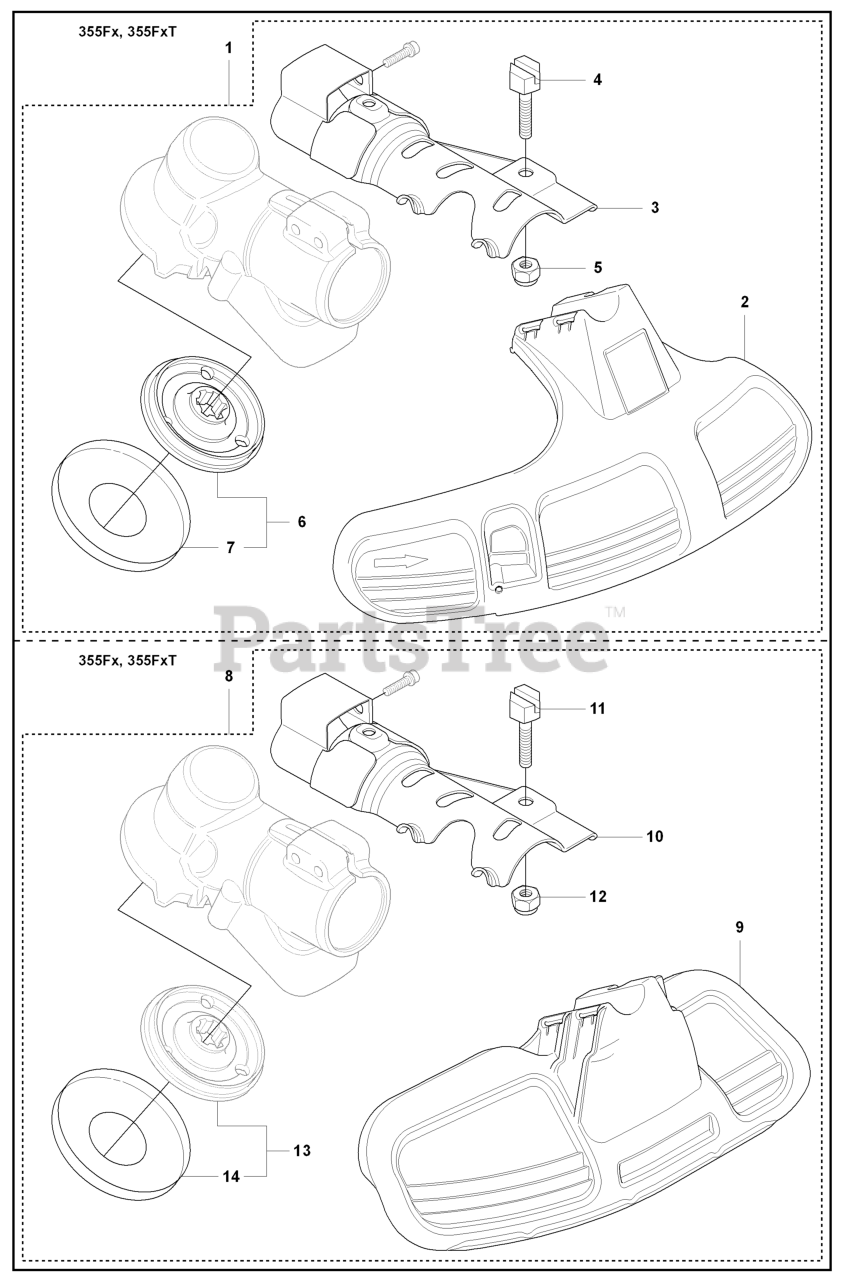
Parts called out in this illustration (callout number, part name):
2	PROTECTION
3	ATTACHMENT PLATE
5	LOCKNUT M6
7	GRASS SEALING
9	BLADE GUARD GRASS
10	ATTACHMENT PLATE
12	LOCKNUT M6
14	GRASS SEALING
